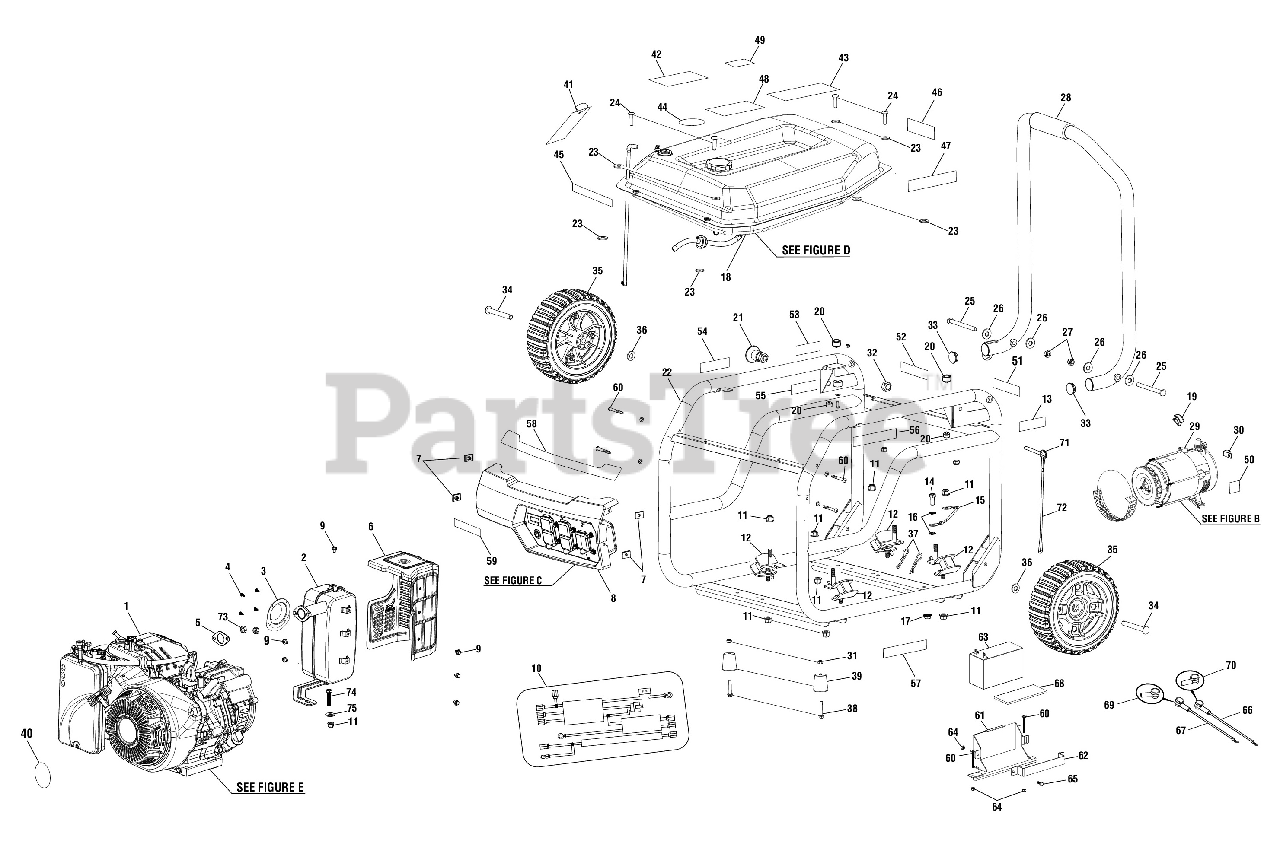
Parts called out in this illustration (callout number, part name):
1	Engine (Ducar 420cc)
3	Spark Arrester Screen
4	Screw (8-32 x 3/8 in., Pan Hd.)
5	Exhaust Gasket
6	Heat Shield
7	U-Clip (M6)
8	Bolt (M6 x 9 mm, Hex Flange Hd.)
9	Bolt (M6 x 9 mm, Hex Flange Hd.)
10	Wire Assembly
11	Lock Nut (M8 x 1.25 mm, Flange)
12	Engine Isolator (Large)
13	Lock Pin Label
14	Bolt (5/16-18 x 3/4 in., Hex. Hd.)
15	Assembly, ground wire
16	Washer (5/16 in., External Star)
17	Flange Nut (5/16-18, Hex Hd.)
18	Fuel System
19	Plug (Generator Head)
20	Rubber Bumper
21	Quick Release Pin Assembly
22	Washer (1/4 in., Type A)
23	Washer (1/4 in., Type A)
24	Screw (1/4-20 x 1 in., T30 Torx Hd.)
25	PIN, HANDLE PIVOT BLACK
26	Washer ( 5/16 in.)
27	Lock Nut (5/16-18, Hex Hd.)
28	Handle Assembly
29	Generator Head Assembly
30	Ground Lug (5/16-24) (BM903600)
31	Lock Nut (M8 x 1.25)
32	Lock Nut (1/2-20, Hex)
33	End Cap (Handle)
34	Washer (M10)
35	Handle Isolator
36	Washer (OD19.75 x ID10.5 x 1t)
37	Hitch Pin (M3)
38	Bolt (M8 x 1.25 in., Flange Hex Hd.)
39	Foot Assembly
40	Engine Recoil Label
41	Warning Hangtag
42	Danger Icon Warning Label
43	CPSC (English) Label
44	Remove Cap Fuel Stabilizer Label (English)
45	Logo Label
46	UL Fire Warning Label Spark Arrestor)
47	Start Label
48	Fuel Stabilizer Label (French/Spanish)
49	No E85 Label
50	Ground Label Icon
51	Ground Warning Label
52	Risk of Fire Danger Label
53	Quick Release Pin Label
54	Inquires Label (Ryobi)
55	Hot Surface and Exhaust Label
56	Fire Distance Label (Eng/Sp)
57	Engine Lubricant Label
58	Performance Label
59	Choke Label
60	Screw (M6 x 50 mm, T30 Torx Pan Hd. )
61	Battery Box Gasket
62	Battery Hold Down Bracket Assembly
63	Battery Bracket
64	Lock Nut (M6 x 1 mm)
65	Screw (M6 x 16 mm, Hex Hd.)
66	Battery Cable (Red)
67	Battery Cable (Black)
68	Gasket (Battery Hold Down Bracket)
69	Battery Cable (Black)
70	Rubber Battery Cable Boot (Red)
71	Release Pin (5/16 x 2 in.)
72	Lanyard (3/16 in.)
73	Hex Nut (M8 x 1.25, Special)
74	Screw (M8 x 40 mm, Hex Hd.)
75	Washer (ID9 x OD25.4 x 2t)
